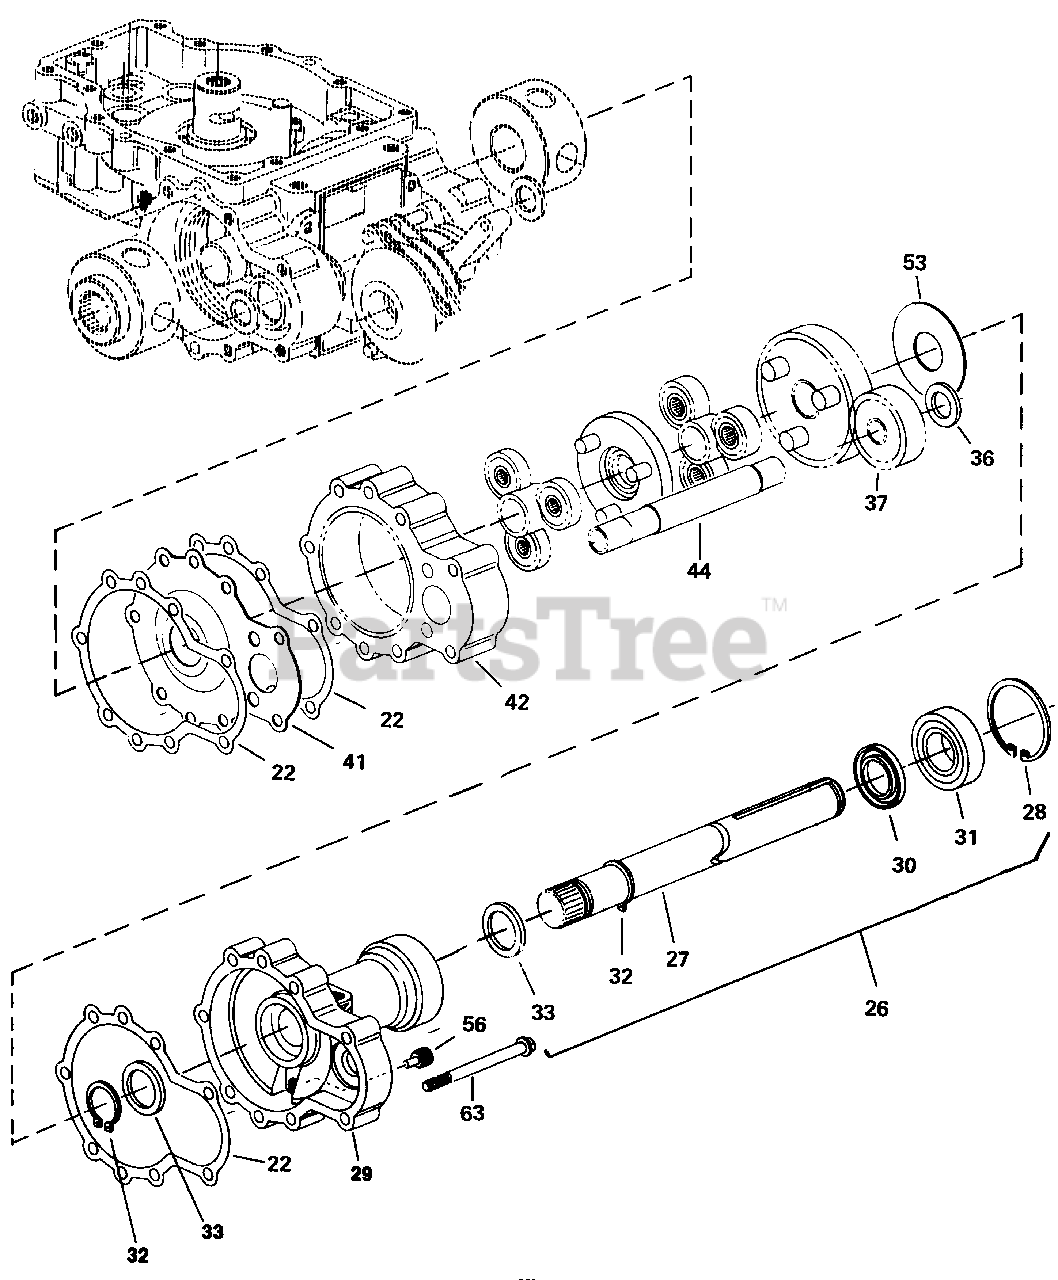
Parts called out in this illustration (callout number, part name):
22	GASKET, Axle Housing
26	AXLE HOUSING, S/A-B
27	SHAFT, Axle
28	RETAINING RING, Internal
29	HOUSING, Axle-B
30	LIP SEAL, Radial
31	BEARING, Ball
32	RING, Retainer
33	WASHER, Thrust
37	LOCK GEAR, Differential
41	PLATE, Wear
42	RING CEAR, A & B S/A, 57T
44	BRAKE SHAFT-B
53	WASHER, Thrust
56	PLUG, Magnetic
63	CAPSCREW, 1/4-20 Hex Flange x 2-3/4
63	GASKET OVERHAUL KIT (Incl. Ref. Nos. 19, 22 & 24)
